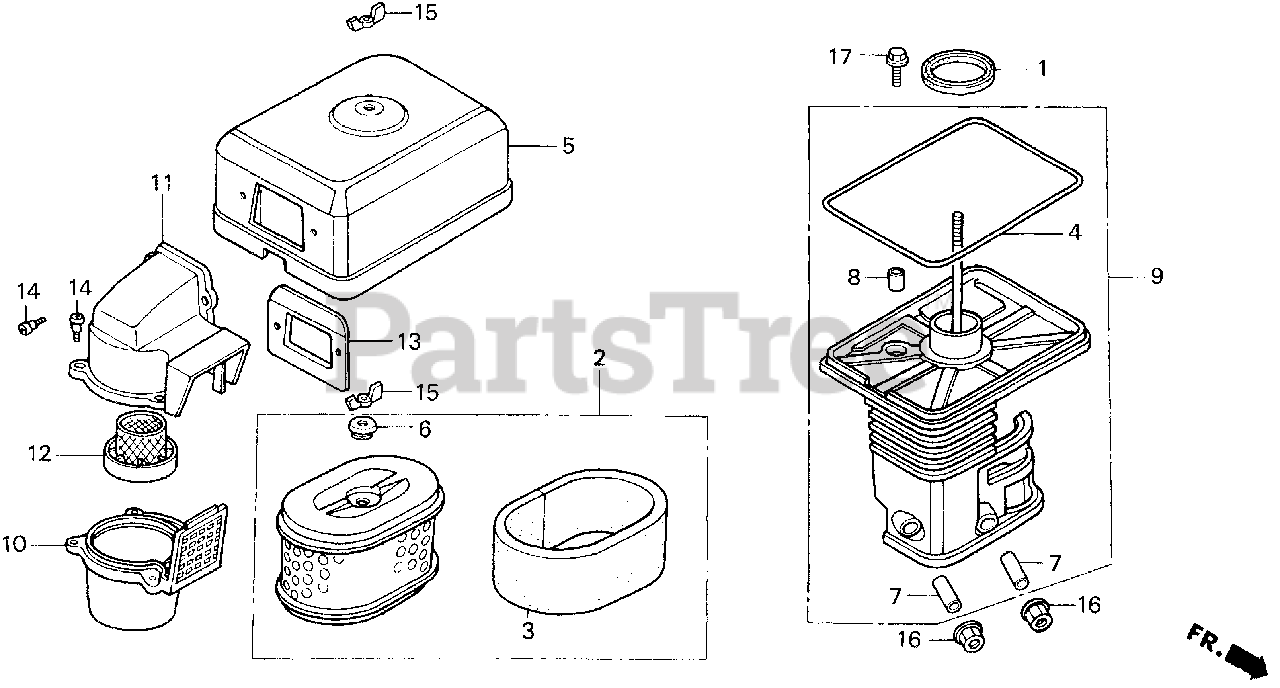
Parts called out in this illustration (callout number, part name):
1	GASKET, ELBOW
2	ELEMENT, AIR CLEANER (DUAL)
3	FILTER (OUTER)
4	GASKET, AIR CLEANER COVER
5	COVER, AIR CLEANER (DUAL)
6	GROMMET, AIR CLEANER
7	COLLAR, AIR CLEANER
8	COLLAR B, AIR CLEANER
9	ELBOW, AIR CLEANER
10	CASE, PRE AIR CLEANER
11	CAP, PRE AIR CLEANER
12	GUIDE, PRE AIR CLEANER
13	PLATE, PRE AIR CLEANER
14	BOLT, MUDGUARD
15	WINGNUT, TOOL BOX SETTING
16	NUT, FLANGE (6MM)
17	BOLT, FLANGE (6X20)
